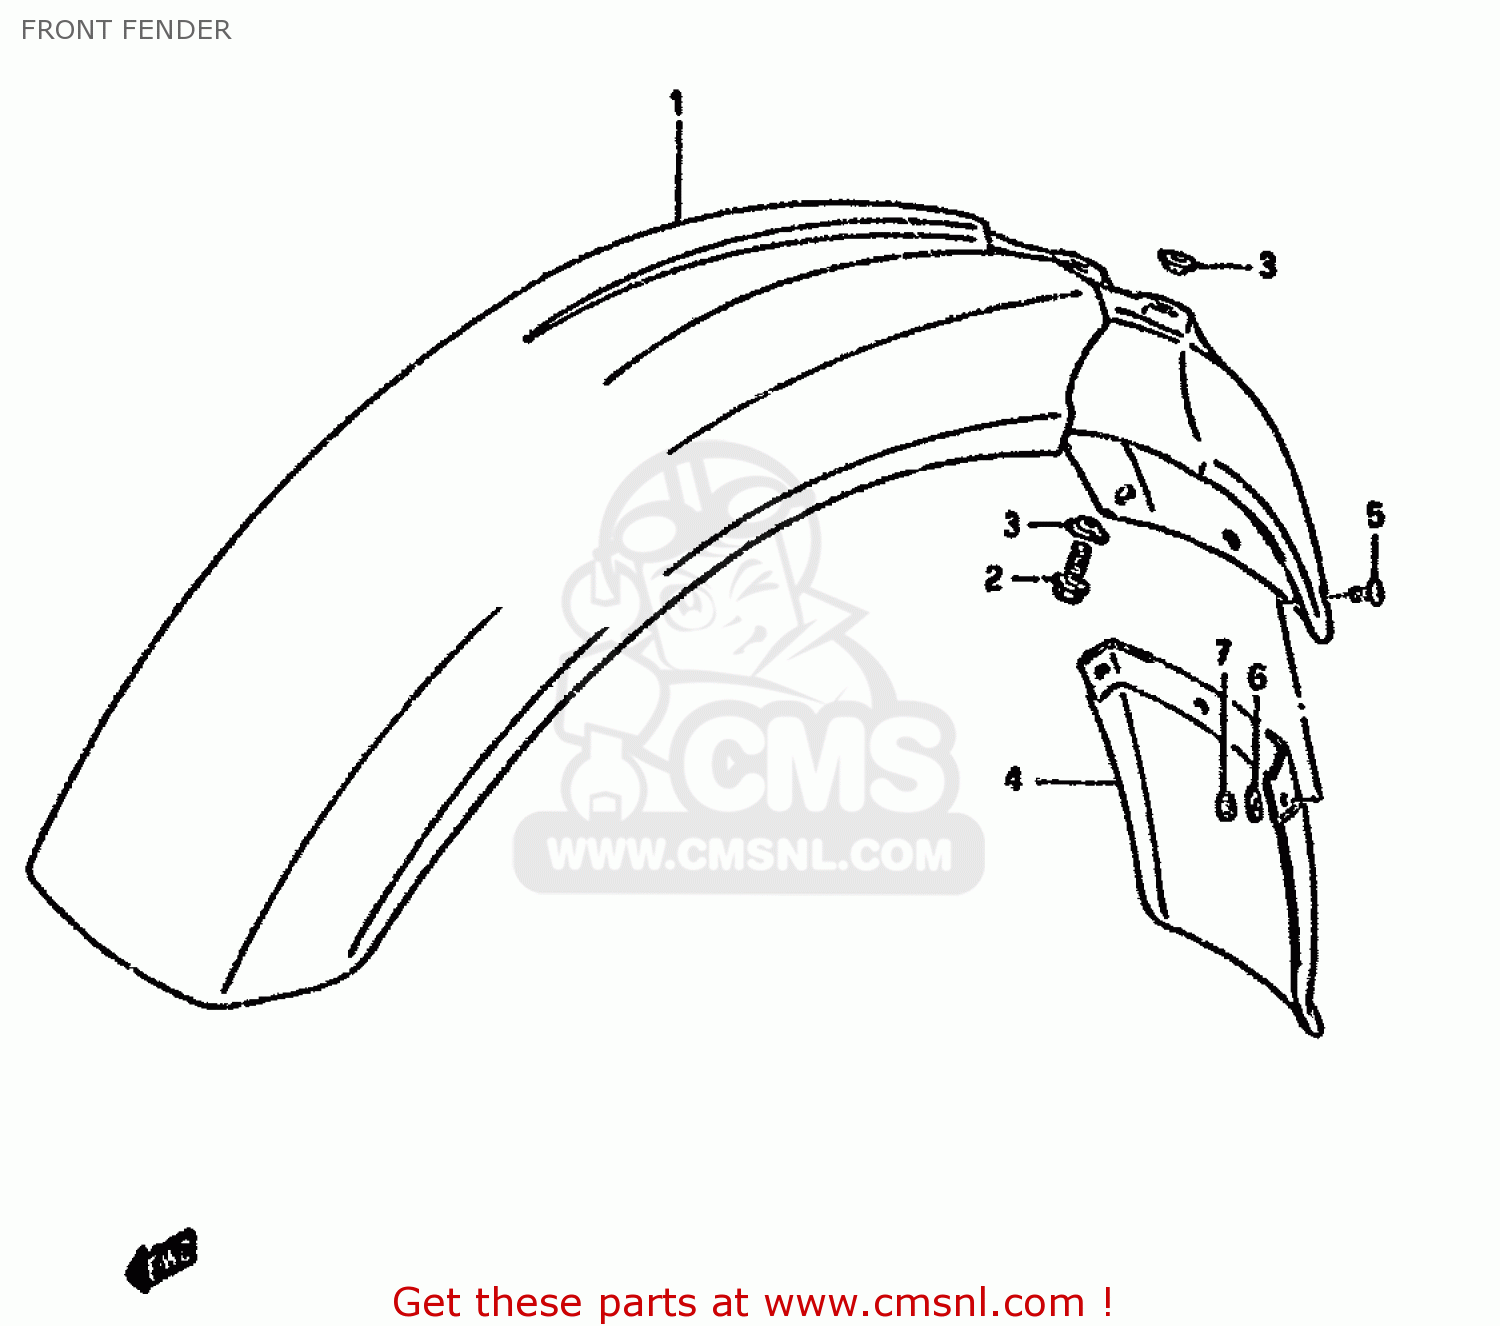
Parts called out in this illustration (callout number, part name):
1	FENDER,FR
2	BOLT
3	WASHER
4	MUD GUARD, FRONT FENDER
5	SCREW(5X10)
6	WASHER
7	NUT
